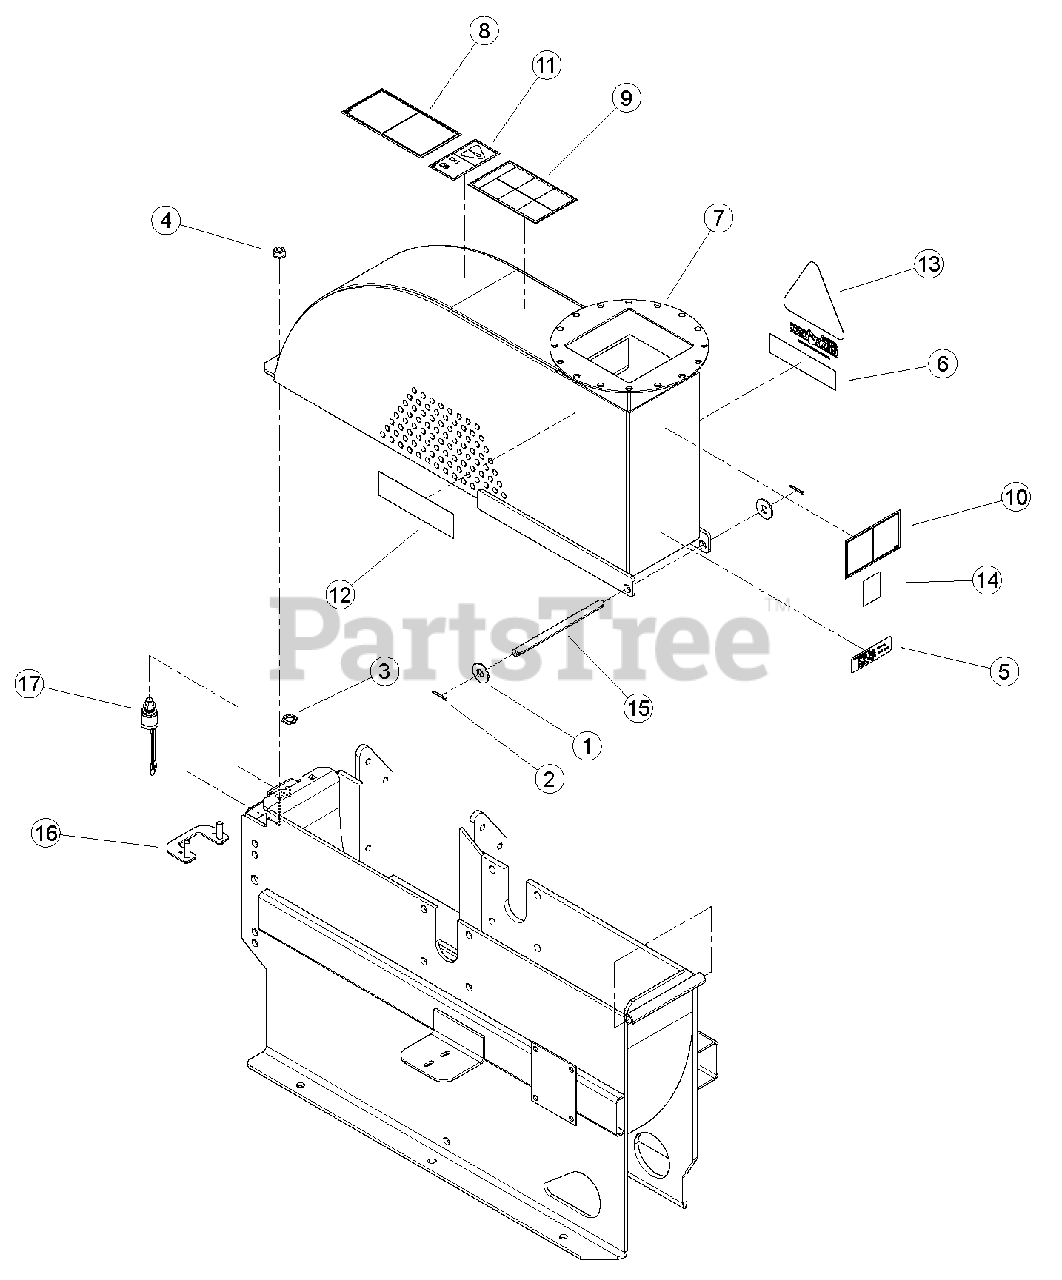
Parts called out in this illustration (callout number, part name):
1	WASHER, 1/2" FLAT ZP
2	PIN, 1/8 X 1.00 ZP COTTER
3	NUT, 5/8-32 JAM
4	NUT, 3/8-16 NYLOCK FLANGE
5	DECAL, ATLANTIC BRIDGE LTD INFO (CE COMPLIANT ONLY)
6	DECAL, MODEL CH8993H
7	ASSEMBLY, CHIPPER COVER W/DECALS
8	DECAL, KNIFE ACCESS ISO
9	DECAL, OPERATING INSTRUCTIONS ISO
10	DECAL, DISCHARGE ISO
11	DECAL, MAINTENANCE ISO
12	DECAL, ECHO BEARCAT 6.82 X 1.90
13	DECAL, CHIP IT
14	DECAL, ECHO BEARCAT QR CODE
15	SHAFT, CHIPPER TOP PIVOT
16	WELDMENT, CHIPPER HOUSING ACCESS
17	ASSEMBLY, SEALED SWITCH
